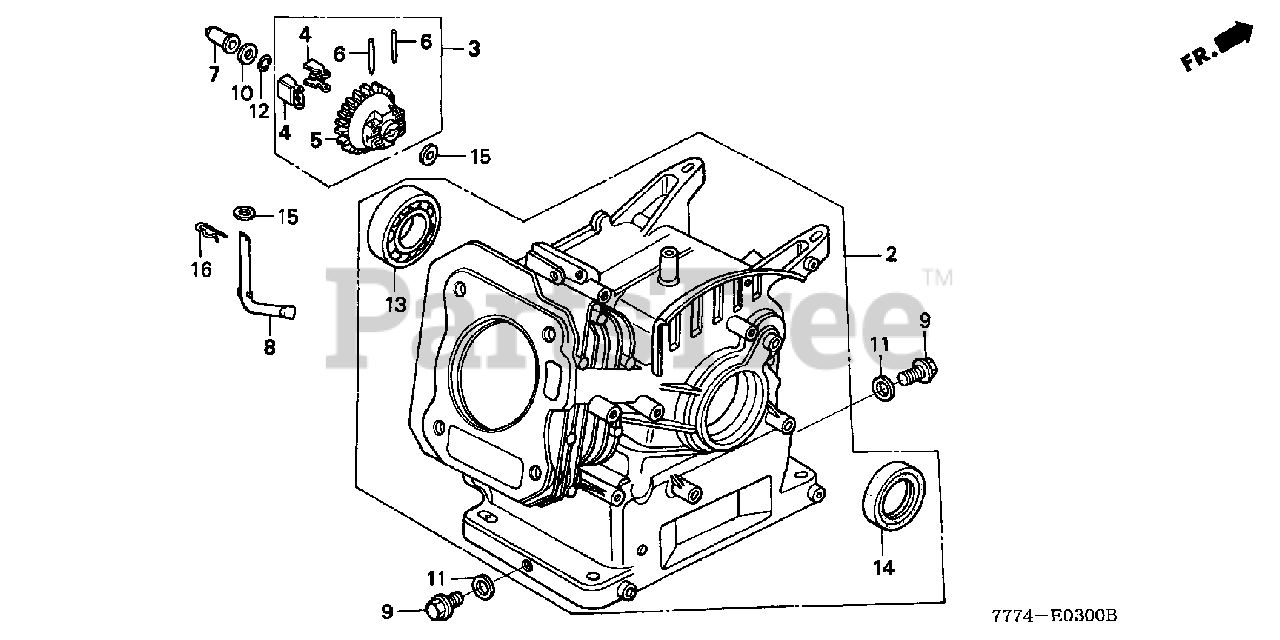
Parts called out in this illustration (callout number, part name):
2	CYLINDER ASSY.
3	GOVERNOR ASSY.
4	WEIGHT, GOVERNOR
5	HOLDER, GOVERNOR WEIGHT
6	PIN, GOVERNOR WEIGHT
7	SLIDER, GOVERNOR
8	SHAFT, GOVERNOR ARM
9	BOLT, DRAIN PLUG
10	WASHER, THRUST (6MM)
11	WASHER, DRAIN PLUG (10.2MM)
12	CLIP, GOVERNOR HOLDER
13	BEARING, RADIAL BALL (6205)
14	OIL SEAL (25X41X6)
15	WASHER, PLAIN (6MM)
16	PIN, LOCK (8MM)
